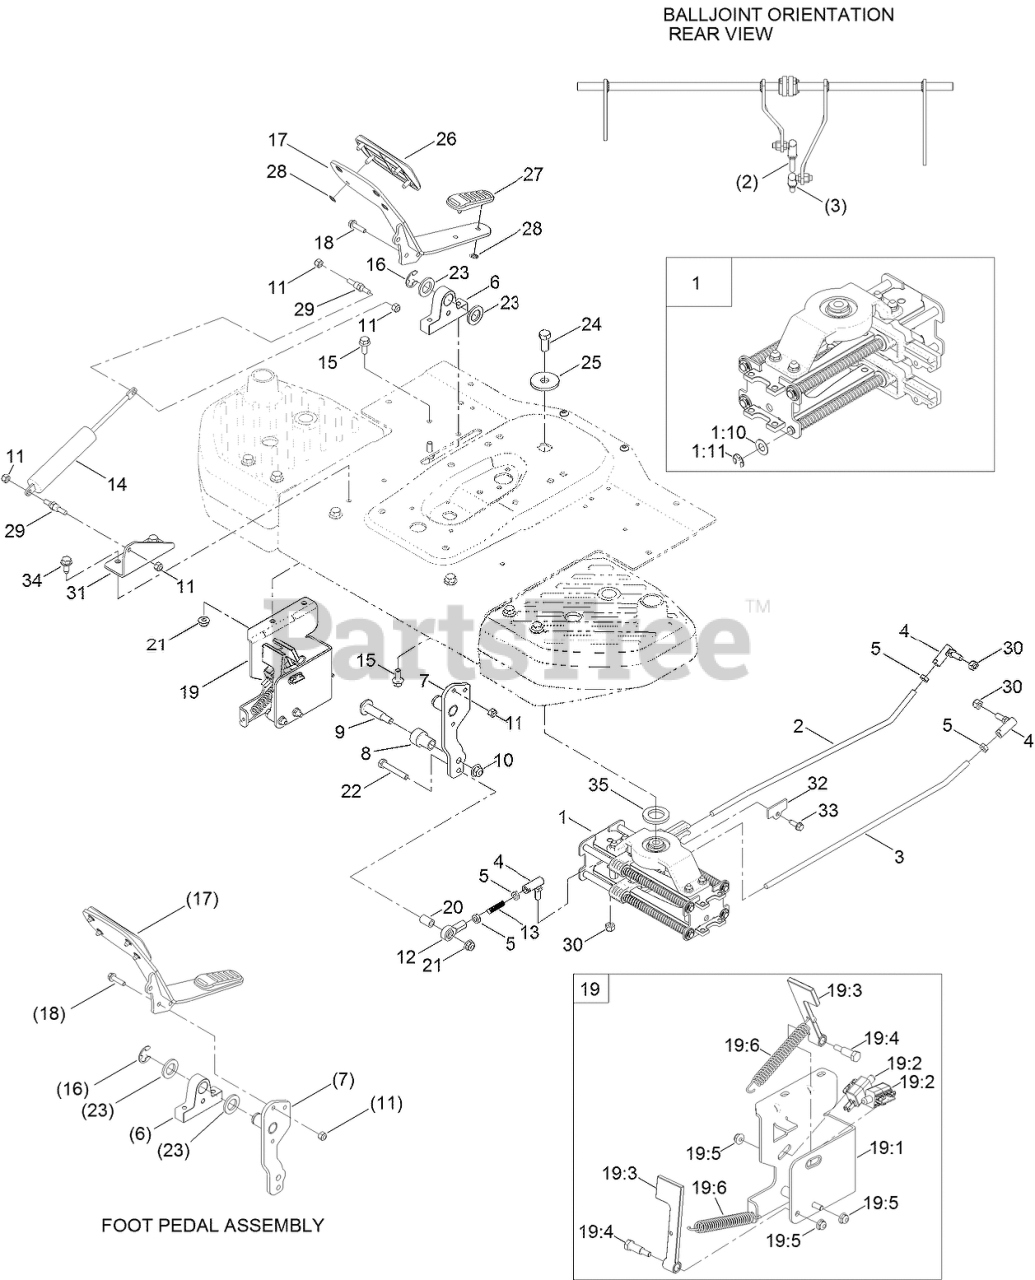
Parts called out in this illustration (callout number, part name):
1	SPEED CONTROL ASM
1:10	WASHER-THRUST
1:11	E-RING
2	ROD-HYDRO, RH
3	ROD-HYDRO, LH
4	BALLJOINT-RH (W/GROMMET)
5	NUT-JAM
6	MOUNT-PEDAL PIVOT
7	PIVOT LEVER ASM
8	ROLLER
9	BOLT-WHEEL
10	NUT-HF, NI
11	NUT-LOCK, NI
12	BALLJOINT-RH
13	ROD-THREADED
14	DAMPER-NON CAVITATING
15	SCREW-HHF
16	E-RING
17	PEDAL-TRACTION
18	SCREW-HHF
19	NEUTRAL RETURN ASM
19:1	BRACKET-SWITCH
19:2	SWITCH
19:3	ARM-SWITCH
19:4	BOLT-SHOULDER
19:5	NUT-HF
19:6	SPRING-EXTENSION
20	SPACER
21	NUT-HF, NI
22	SCREW-HH
23	WASHER
24	SCREW-HH
25	WASHER-THRUST
26	PAD-TOE, HYDRO PEDAL
27	PAD-HEEL, HYDRO PEDAL
28	NUT-PUSH
29	STUD-DAMPER
30	NUT-LOCK
31	BRACKET-DAMPER
32	COVER-END ROD
33	SCREW-HWH, THREAD ROLL
34	SCREW-HWHTF
35	SPACER-BEARING
